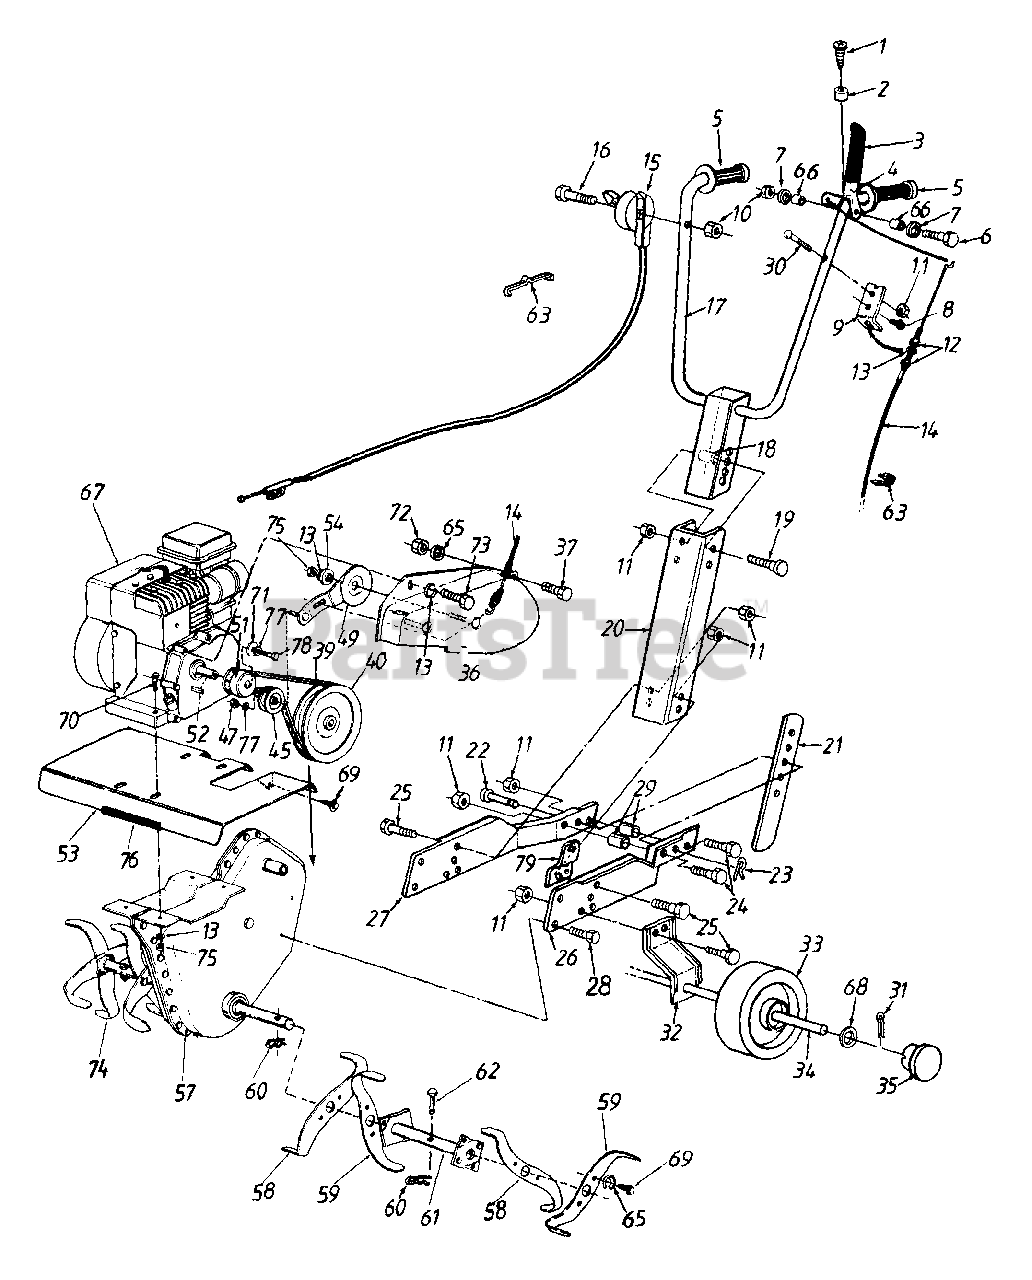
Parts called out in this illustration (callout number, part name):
1	Tap Scr. #10-16 x 1/2" Lg.
2	Rubber Bumper
3	Vinyl Grip
5	Handle Grip
6	Hex Bolt 1/4-20 x 2" Lg.
7	Fl-Wash. 1/4" I.D.
8	Hex Tap Scr. 1/4-20 x 1/2" Lg.
9	Cable Bracket
10	Lock Nut 1/4-20 Thd.
11	Lock Nut 5/16-18 Thd.
12	Hex Jam Nut 5/16-24 Thd.
13	L-Wash. 5/16" l.D.
14	Clutch Control Cable
15	Throttle Control
16	Hex Bolt 1/4-20 x 1-1/2" Lg.
19	Carr. Bolt 5/16-18 x 2-1/2" Lg.
23	Hairpin Cotter
24	Hex Bolt 5/16-18 x 1" Lg.
25	Hex Bolt 5/16-18 x 5/8" Lg.
29	Spacer
30	Hex Bolt 5/16-18 x 1/2" Lg.
31	Cotter Pin
34	Axle-Wheel
35	Hub Cap
39	V-Belt
40	Pulley - Chain Case
45	Flat Idler Pulley
47	Hex Jam L-Nut 3/8-24 Thd.
51	Engine Pulley
52	Square Key 3/16" x .75" Lg.
57	Chain Case Ass'y. Comp.
63	Cable Tie - Plastic
65	L-Wash. 1/4" I.D."
66	Spacer
67	Engine
68	Fl-Wash. 3/8" l.D.
69	Tap Scr. 1/4-20 x 1/2" Lg.
70	Hex Bolt 5/16-18 x 1-1/2" Lg.
71	Fl-Wash. 3/8" I.D. x 1" O.D.
72	Hex Nut 1/4-20 Thd.
73	Hex Bolt 5/16-24 x .5" Lg.
76	Trim Strip
77	L-Wash. 3/8" I.D.
78	Hex Bolt 3/8-24 x 1" Lg.
